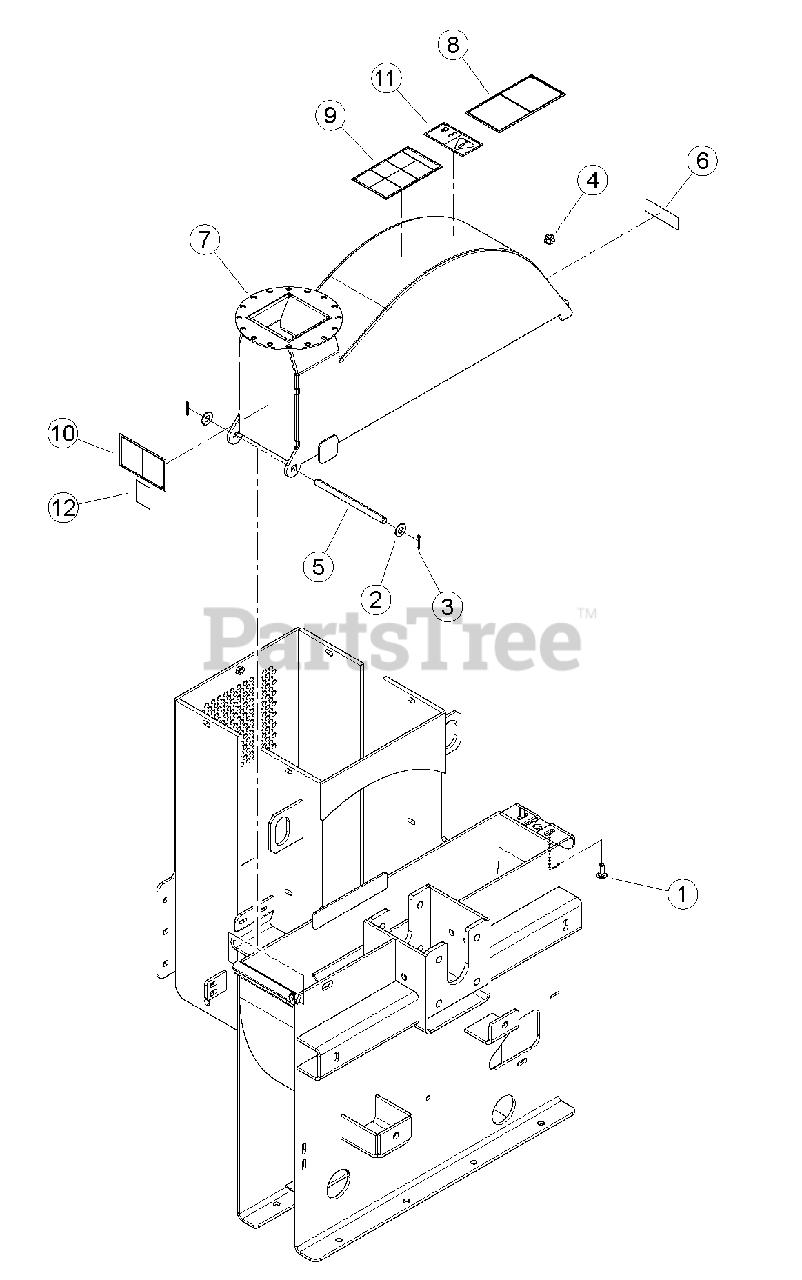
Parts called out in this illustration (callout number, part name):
1	BOLT, 3/8 X 1" GR5 CRG NC ZP
2	WASHER, 1/2"SAE FLAT ZP
3	PIN, 1/8 X 1.00 ZP COTTER
4	NUT, 3/8-16 NYLOCK FLANGE
5	SHAFT, CHIPPER TOP PIVOT
6	DECAL, ATLANTIC BRIDGE LTD INFO (CE COMPLIANT ONLY)
7	ASSEMBLY, CH611DH CHIPPER HOUSING TOP
8	DECAL, KNIFE ACCESS ISO
9	DECAL, OPERATING INSTRUCTIONS ISO
10	DECAL, DISCHARGE ISO
11	DECAL, MAINTENANCE ISO
12	DECAL, ECHO BEARCAT QR CODE
